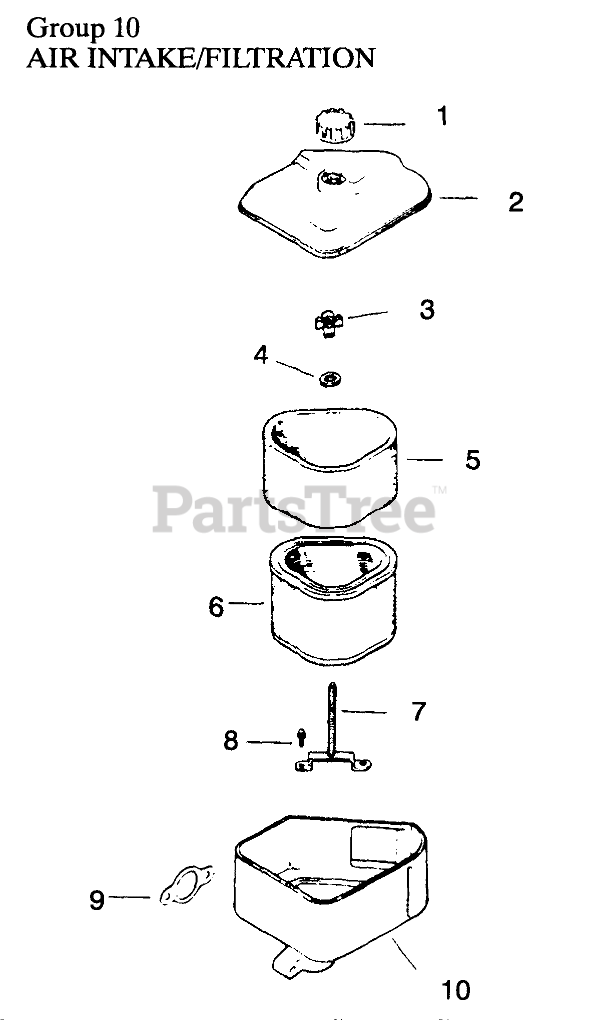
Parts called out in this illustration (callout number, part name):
1	Knob-Air Cleaner Cover
2	Cover-Air Cleaner
3	Wingnut
4	Washer
5	Element-Precleaner
6	Element-Air Cleaner
7	Stud-Mounting Plate
8	Screw
9	Gasket-Air Cleaner
10	Base-Air Cleaner
